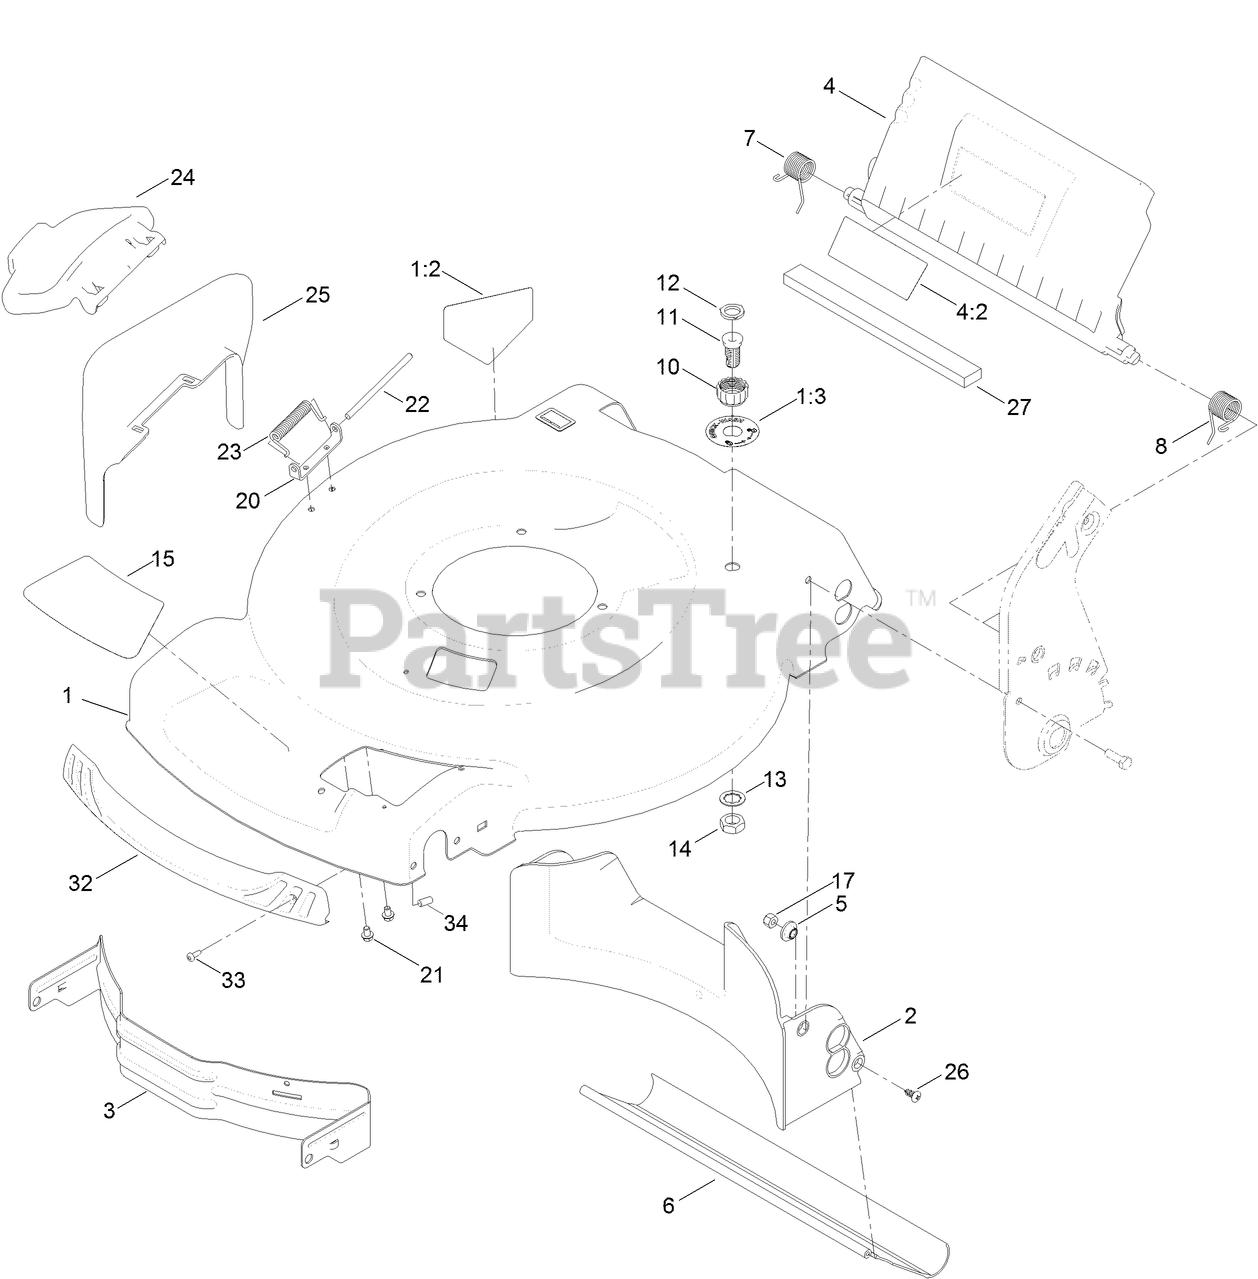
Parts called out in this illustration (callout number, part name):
1:2	DECAL-DANGER
1:3	DECAL-PORT, WASHOUT
2	BAFFLE-REAR
3	BAFFLE-FRONT
4	REAR DEFLECTOR ASM
4:2	DECAL-WARNING
5	WASHER-STEPPED, BAFFLE
6	SHIELD-TRAILING
7	SPRING-TORSION
8	SPRING-TORSION
10	COUPLING-HOSE, WASHOUT PORT
11	PORT-WASHOUT
12	WASHER-SEAL, WASHOUT PORT
13	WASHER-LOCK
14	NUT-JAM
15	DECAL-DECK
17	NUT-LOCK, NI
20	BRACKET-COVER
21	SCREW-HWH
23	SPRING-TORSION
24	DEFLECTOR-SIDE
25	CHUTE-DISCHARGE, SIDE
26	SCREW-PTH
27	FOAM-SEAL
32	BUMPER
33	SCREW-FORMING, THREAD
34	CAP-PLUG
